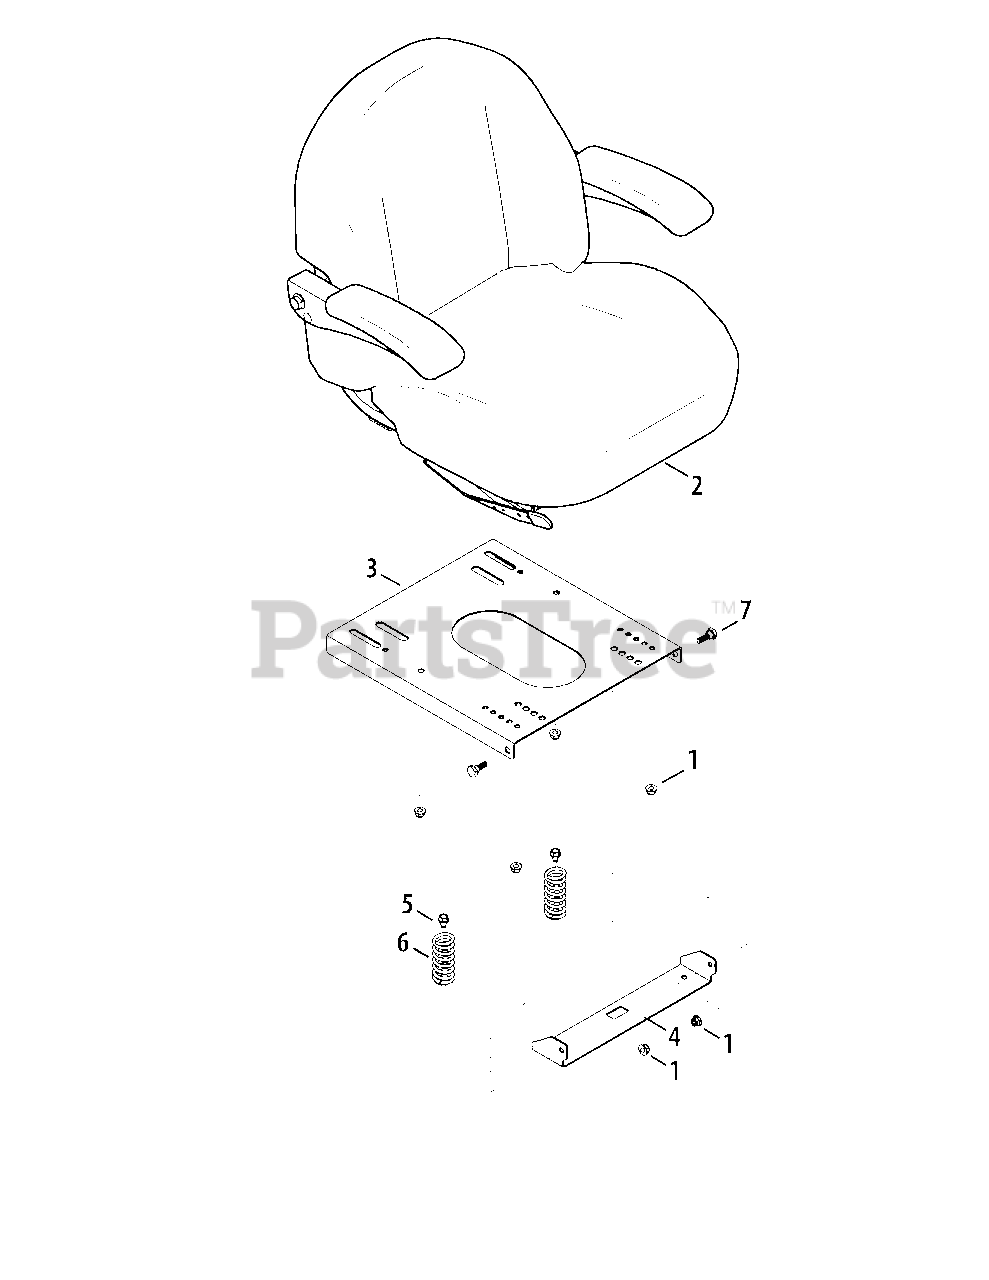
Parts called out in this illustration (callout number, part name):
1	Flange Lock Nut, 5/16-18
3	Seat Plate
5	Hex Washer Screw, 5/16-18 x .750
6	Compression Spring, 1.71 x 3.25 x .23
7	Shoulder Screw, 5/16-18 x .437 x .268
